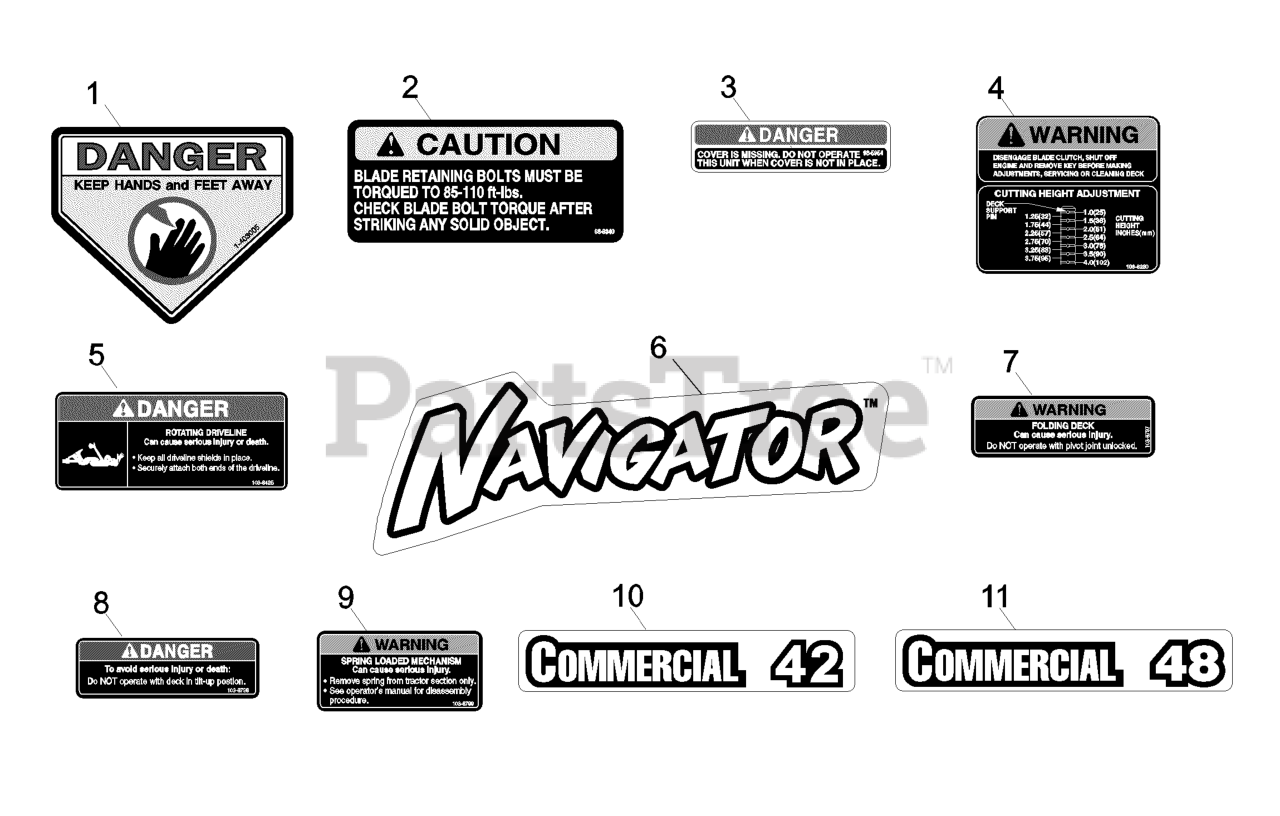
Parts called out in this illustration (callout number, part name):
1	DECAL-DANGER
2	DECAL-TORQUE
3	DECAL-COVER, MISSING
5	DECAL-DRIVELINE
6	DECAL,NAVIGATOR MODEL
7	DECAL-FOLDING DECK
8	DECAL-DANGER
9	DECAL-SPRING
10	DECAL,COMMERCIAL 42
11	DECAL,COMMERCIAL 48
